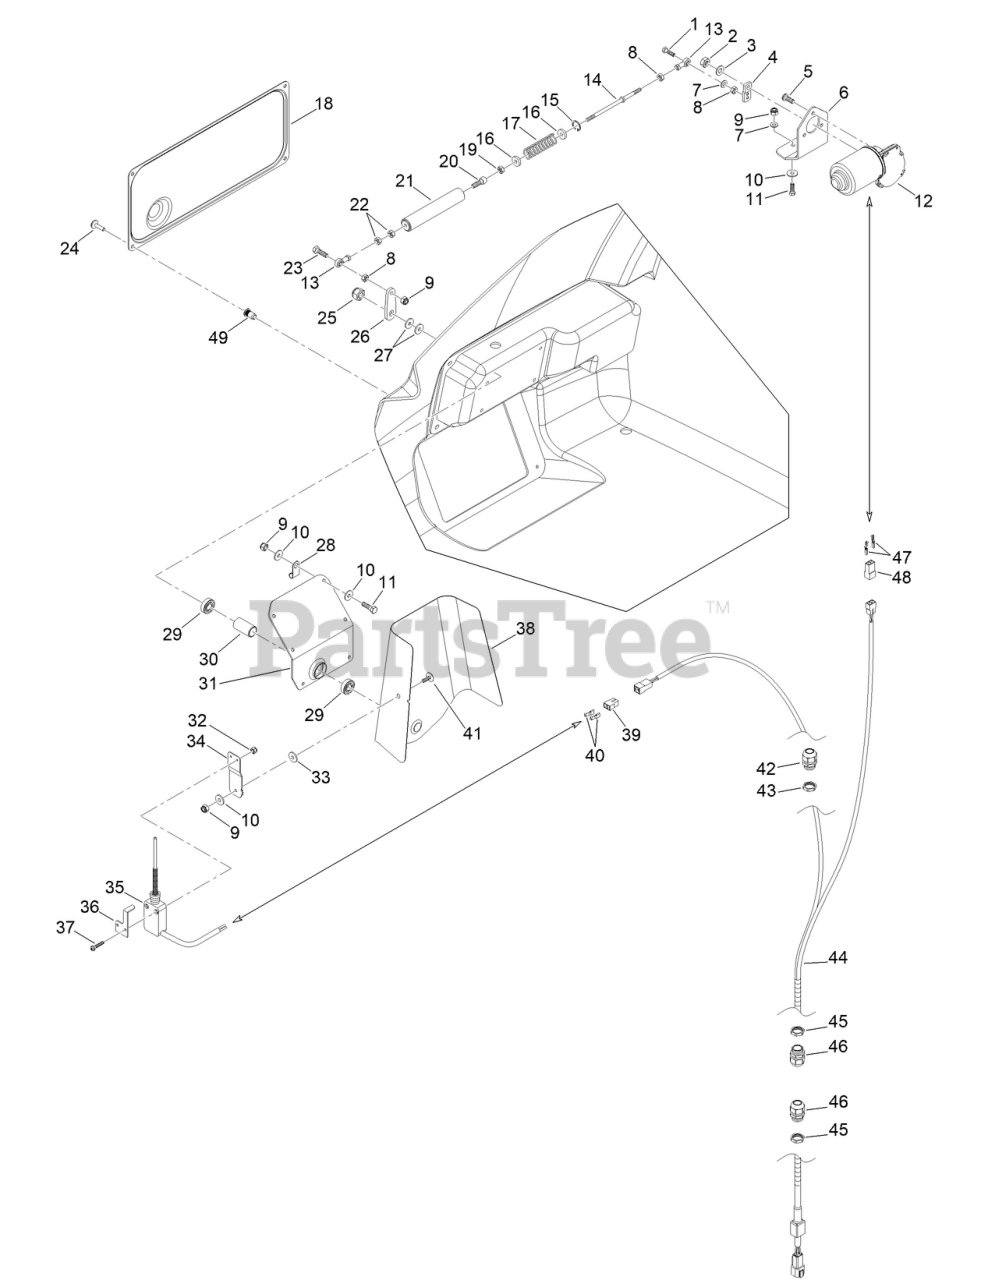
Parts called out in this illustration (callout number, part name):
3	WASHER
4	PLATE, HOPPER-SPREADER
6	SUPPORT-ENGINE
7	WASHER
10	WASHER
12	BAFFLE-MOTOR
13	HEAD-JOINT
14	SHOCK ABSORBER, GRASS SPREADER
15	RING-RETAINING, INT
16	WASHER
17	SPRING
21	BODY SHOCK KIT
23	SCREW-HH
24	SCREW-FLANGE
26	LEVER-HOPPER
27	SPACER
28	GROMMET
29	BEARING
30	SPACER
31	SUPPORT-SPREADER
33	WASHER-BELLEVILLE
34	SUPPORT-SENSOR, CATCHER
35	MICROSWITCH, HOPPER
36	BRACKET
38	MANIFOLD
39	CONNECTOR-ELECTRIC
40	CAP-CABLE END, FEMALE
42	FITTING-UNION
43	NUT-PLASTIC
44	WIRING-CATCHER, GRASS
46	FITTING, CABLE
47	CONNECTOR
48	CONNECTOR-ELECTRIC
49	NUTSERT-BLIND
